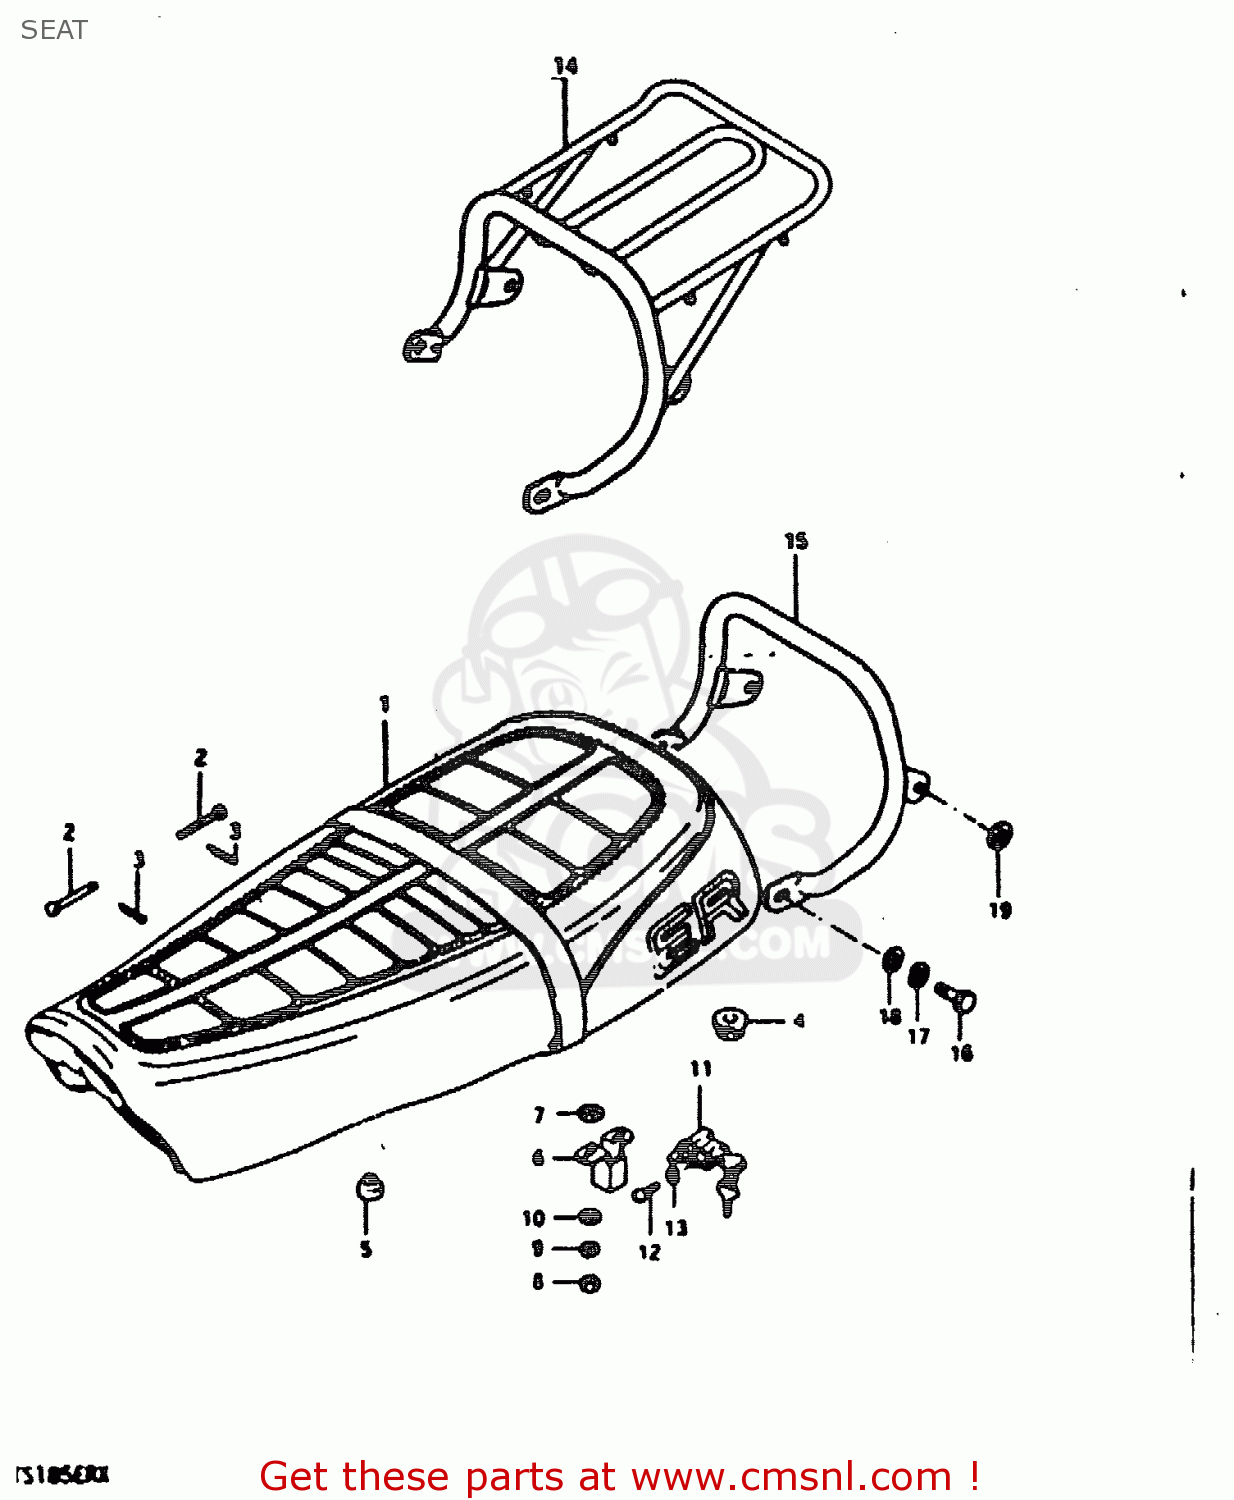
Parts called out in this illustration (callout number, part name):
1	SEAT ASSY
2	PIN
3	PIN
4	CUSHION
5	CUSHION
6	PLATE,CLAMP GUIDE
7	WASHER(8.5X18X1)
8	NUT
9	LOCK WASHER
10	WASHER
11	LOCK ASSY,SEAT
12	SCREW
13	LOCK WASHER
14	CARRIER,SPORT
